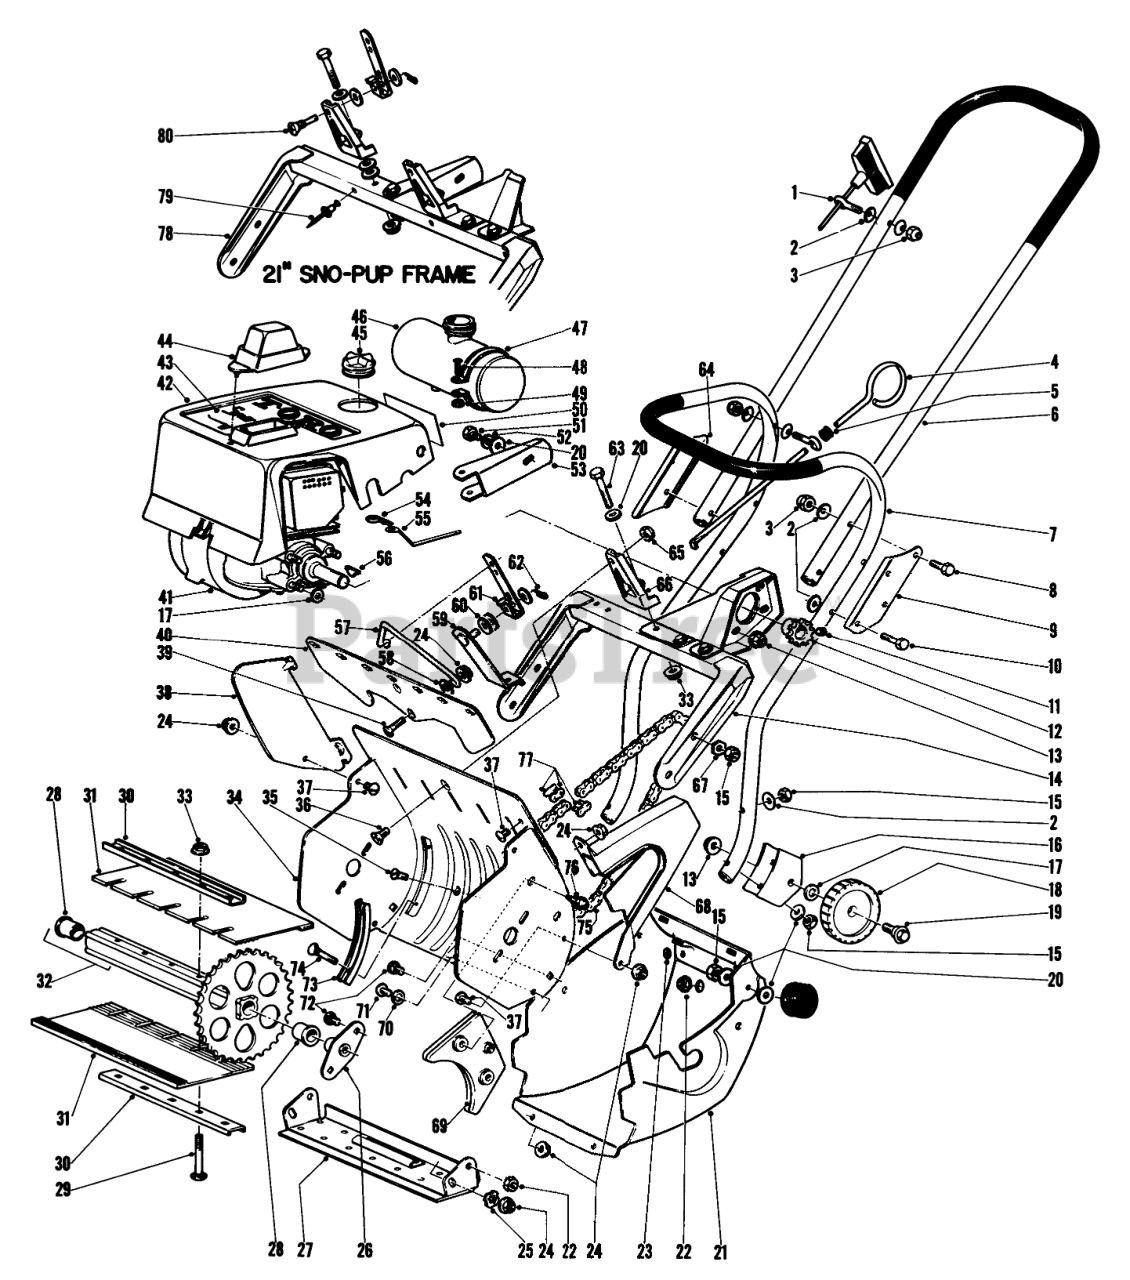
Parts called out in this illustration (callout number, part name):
1	Bolt-Eye
2	WASHER
3	NUT-CAP
4	Vane Adj. Rod
5	GROMMET
6	Handle Upper
7	Handle Lower
9	SPLICE PLATE
11	SCREW-SET, HSH
12	SPROCKET
13	NUT-HHF
14	Frame Assembly
15	Nut
16	Bracket Wheel
17	WASHER-PLAIN
18	Wheel
19	Bolt-Shoulder
20	WASHER-FLAT
21	Shroud, Lower
22	NUT-KEPS
23	SNO PUP PLATED EYELET
24	NUT-LOCK, FLANGE
25	Washer
26	Rotor Shaft Assy.
27	Skid, Riveted Assy.
28	Bushing
30	Reinforcing Strap
31	Blade-Rotor
32	Sprocket & Tube W.A. Incl. #37
33	Nut
34	Housing
36	5/16-18X5/8 FLT HD MS
37	SCREW-PTH
38	Vane
39	10-24X1-1/8 FLT HD MS
40	Mount Vane
41	Engine
42	Shroud Incl. Ref. #7
43	Decal
45	Gas Cap
46	Gas Tank Assy. Incl. Ref. #45
47	1/2 GAS TANK CLAMP
48	10-24 X 1 RND HD MS
49	NUT-SQ
50	Decal
51	SCREW-HH
52	WASHER-LOCK/EXT
53	Bracket
54	Cotter Pin
55	Choke, Strap
57	Linkage Vane Adj.
58	WASHER-FLAT
58	Washer
59	Vane Adj. Bracket
60	WASHER-FLAT
61	Bracket-Vane Adj.
62	PIN-COTTER
63	SCREW-HH
64	Plate-Splice
65	NUT-LOCK, NI
66	Stiffener
67	Washer
68	Chain Guard
69	Stripper
70	Washer
71	SCREW-HEAD, PAN
72	SCREW-CARRIAGE
73	Handle Plate
74	SCREW-CARR
75	CHAIN
76	Screw
77	LINK-CONNECTING, NO. 35
78	Frame Assy.
79	RIVET
80	Screw
